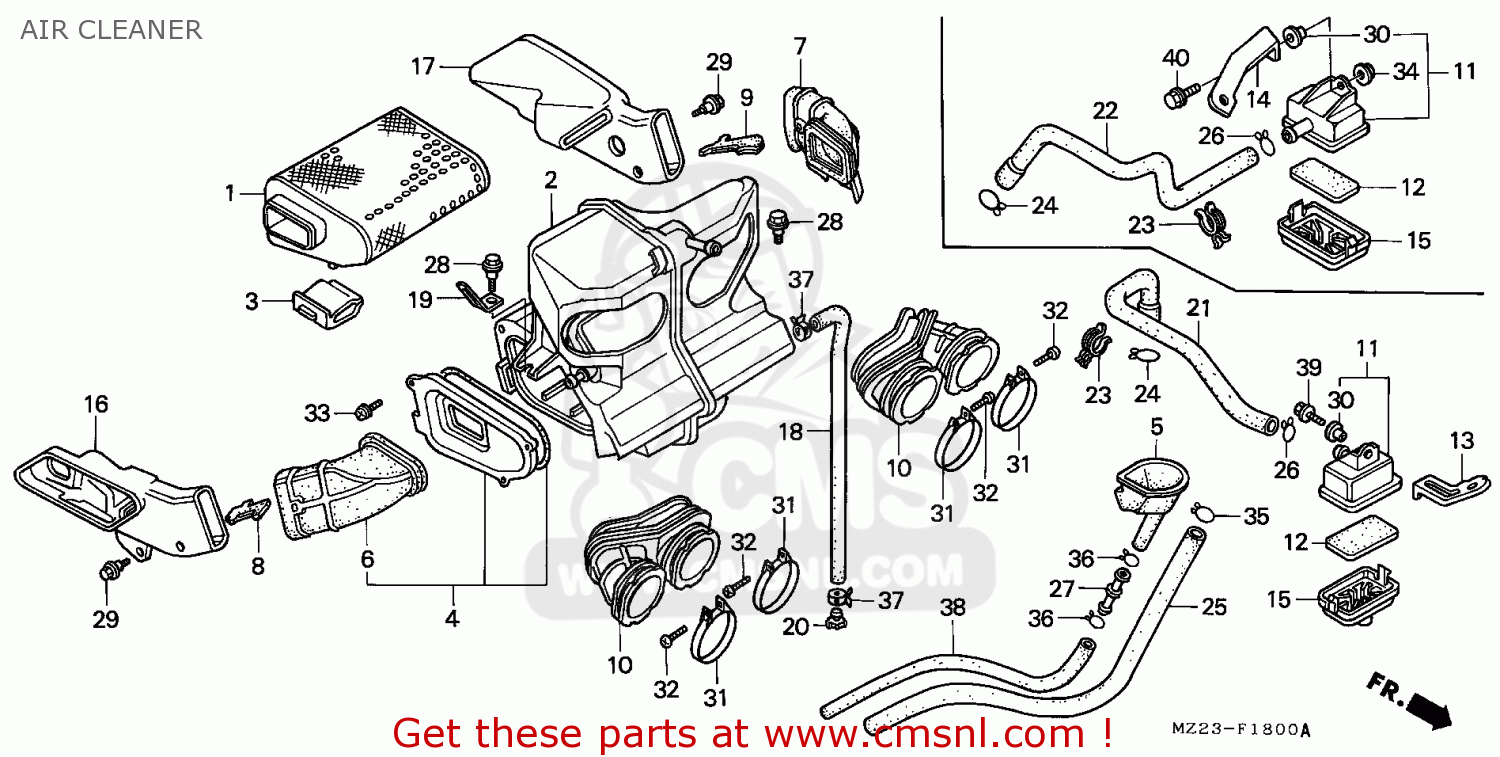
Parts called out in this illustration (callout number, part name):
1	ELEMENT,AIR/C
2	CASE COMP.,AIR/C
3	HOLDER,AIR CLEANE
4	COVER COMP.,AIR C
5	CUP,TANK OVER FLO
6	DUCT,R.AIR CLEANE
7	DUCT,L.AIR CLEANE
8	SEPALATOR,R.DUCT
9	SEPALATOR,L.DUCT
10	TUBE,AIR/C.CONN
11	CASE SUB,AIR CLEA
12	FILTER,SUB AIR CL
13	STAY,SUB AIR CLEA
15	COVER,SUB AIR CLE
16	DUCT,R.RR.INLET
17	DUCT,L INLET RR
18	TUBE,AIR CLEANER
19	CLIP,CANISTER TUB
20	PLUG,BRTHR TUBE
21	TUBE MINI CLEANER
23	HOLDER PB TUBE
24	CLIP,BRTHR.TUBE
25	TUBE,BREATHER TAN
27	JOINT,TUBE
28	BOLT,FLANGE 6MM
29	BOLT,FLANGE 6MM
30	WASHER,CHAIN CASE
31	BAND,AIR CLEANER
32	SCREW,PAN,4X25
33	SCREW-WASH,5X20
36	CLIP,TUBE,B12.5
37	CLIP D12.5 TUBE
38	TUBE,7.3X720
39	BOLT,FLANGE 6X14
